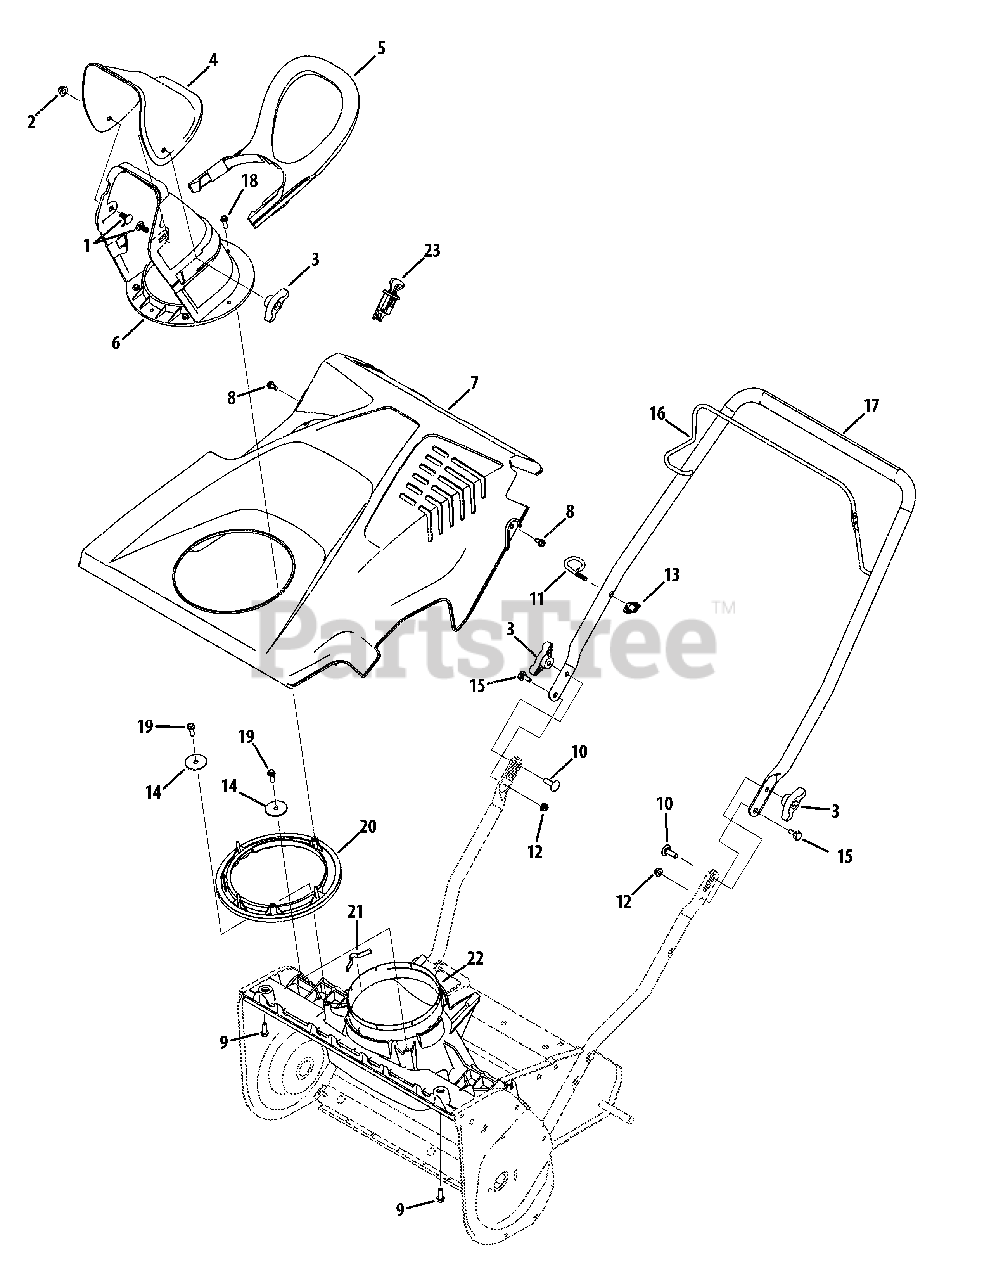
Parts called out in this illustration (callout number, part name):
1	Carriage Bolt, 5/16-18 x .750
2	Flange Lock Nut, 5/16-18
3	Wing Knob, 5/16-18
4	Upper Chute
5	Chute Handle
6	Lower Chute
7	Cover Assembly
8	Hex Washer Screw, 1/4-20 x .625
9	Hex Washer Screw, 1/4-15 x .750
10	Carriage Screw, 5/16-18 x 1.00
11	Eye Bolt, 1/4-20
12	Flange Lock Nut, 1/4-20
13	Handle Knob, 1/4-20
14	Flat Washer, .28 x 1.51 x .066
15	Shoulder Screw, 1/4-20 x .375 x .148
16	Auger Control
17	Upper Handle
18	Hex Washer Screw, 1/4 x .750
19	Hex Washer Screw, 1/4-15 x .750
20	Chute Ring
21	Chute Adjustment Spring
22	Chute Adapter
23	Ignition Switch Assembly
